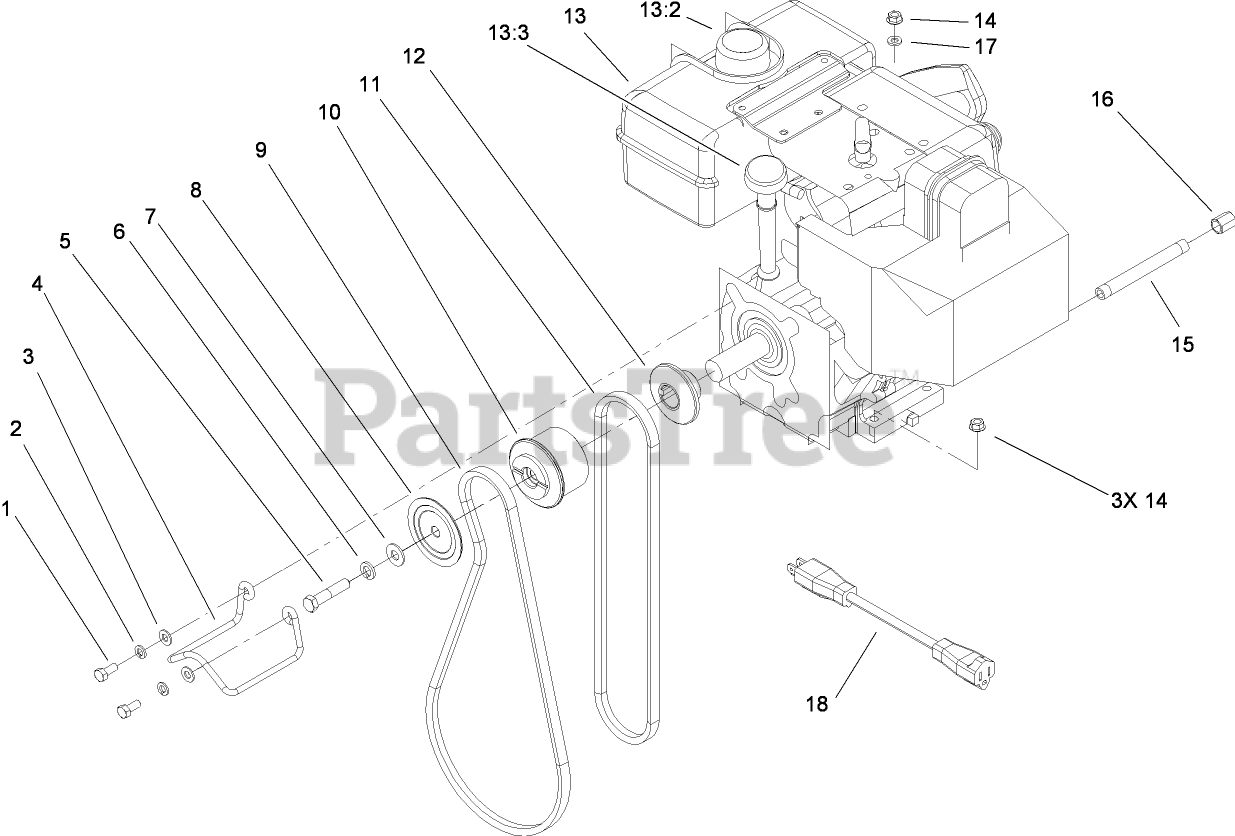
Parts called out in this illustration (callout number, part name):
1	SCREW-HH
2	WASHER-LOCK
3	WASHER-PLAIN
5	SCREW-HH
6	WASHER-LOCK
7	WASHER-FLAT
8	SHEAVE-HALF, IMPELLER
9	BELT-V
10	PULLEY-ENGINE, CENTER
11	V BELT-TRACTION
12	SHEAVE-HALF, TRACTION
13	Loose Parts Package
13:3	DIPSTICK (38652)
14	NUT-HF
15	NIPPLE-PIPE
16	CAP-PIPE
17	WASHER-FLAT
18	CORD-EXTENSION (only on: 38078)
